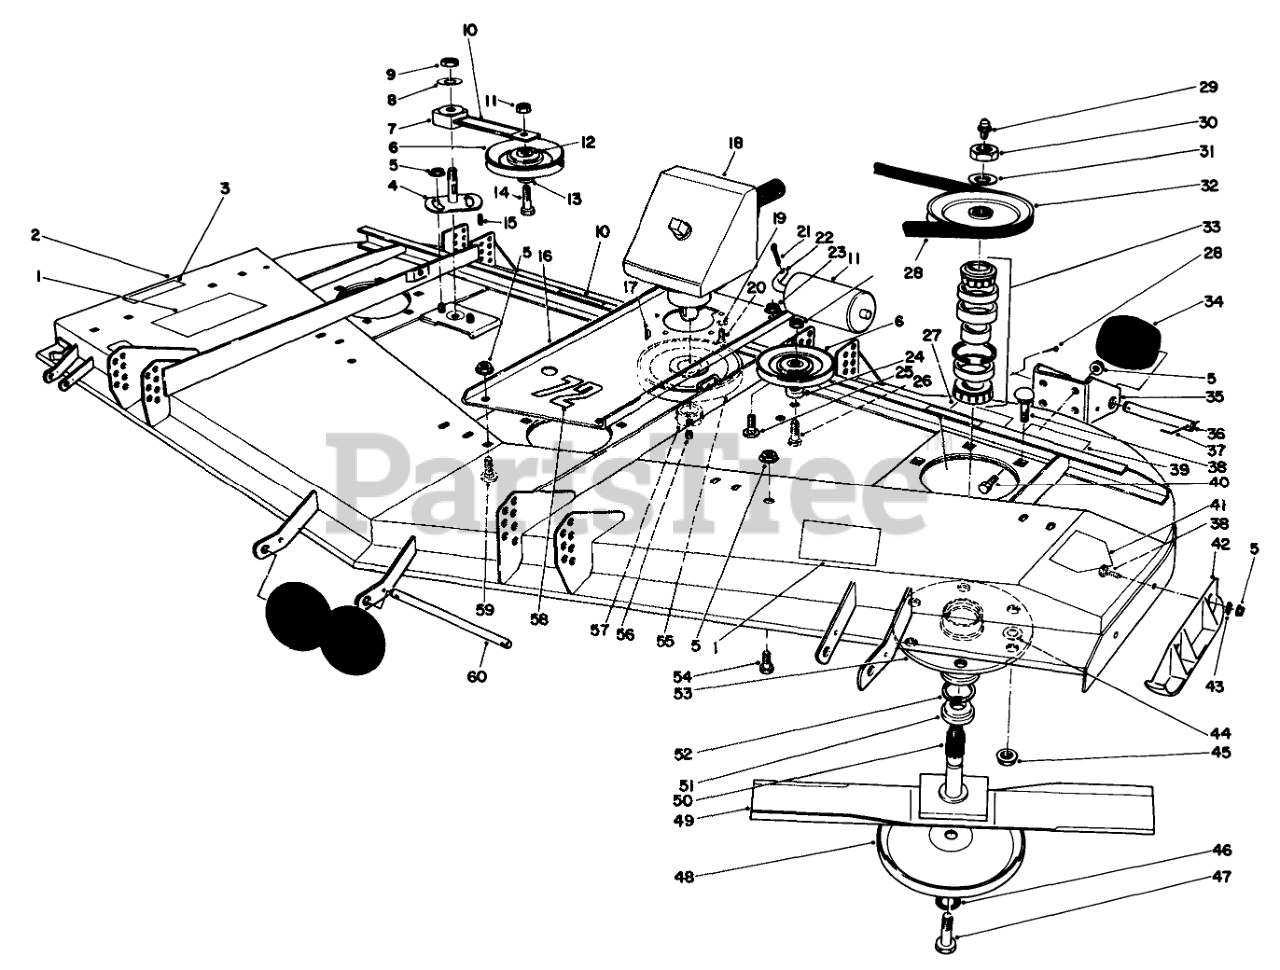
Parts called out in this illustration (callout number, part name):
1	DECAL-DANGER, THROWN OBJECT
2	Housing
3	DECAL-DANGER
4	PLATE-IDLER
5	NUT-HHF, WHIZ
6	PULLEY-IDLER
7	IDLER ARM ASM
8	WASHER-FLAT
9	NUT-LOCK, NI
10	DECAL-DANGER
11	NUT-HEX
12	WASHER-FLAT
13	BUSHING-PULLEY
14	SCREW-HH
15	KEY-SQUARE
16	GEARBOX BASE R
17	KEY-WOODRUFF
18	GEAR BOX ASM
19	WASHER-LOCK
20	SCREW-HSH
21	PIN-COTTER
22	SHAFT-ROLLER, REAR
23	ROLLER-DECK
24	SPACER
25	SCREW-CARR
26	SCREW-HH
27	DECAL-TORQUE
28	V-BELT (72)
29	FITTING-GREASE
30	NUT-HEX
31	WASHER
32	PULLEY & HUB ASM, WELDED
33	BEARING ASM
34	ROLLER
35	Bracket-Roller
36	SHAFT-ROLLER
37	PIN-SPECIAL
38	SCREW-CARR
39	DECAL - WARNING
40	SCREW-HH
41	DECAL-DANGER
42	Skid
43	LOCKWASHER-PYRAMID
44	WASHER-FLAT
45	NUT-HF
46	WASHER-LOCK
47	SCREW-BLADE
48	Cup-Scalp
49	Blade
50	SHAFT
51	SPACER
52	SEAL-OIL
53	HOUSING-SPINDLE
54	SCREW-HH
55	PULLEY WA BO
56	SCREW-SET, HSH
57	Bushing Taper Lock (Incl. Ref. #56)
58	DECAL
59	SCREW-CARR
60	SHAFT-ROLLER
